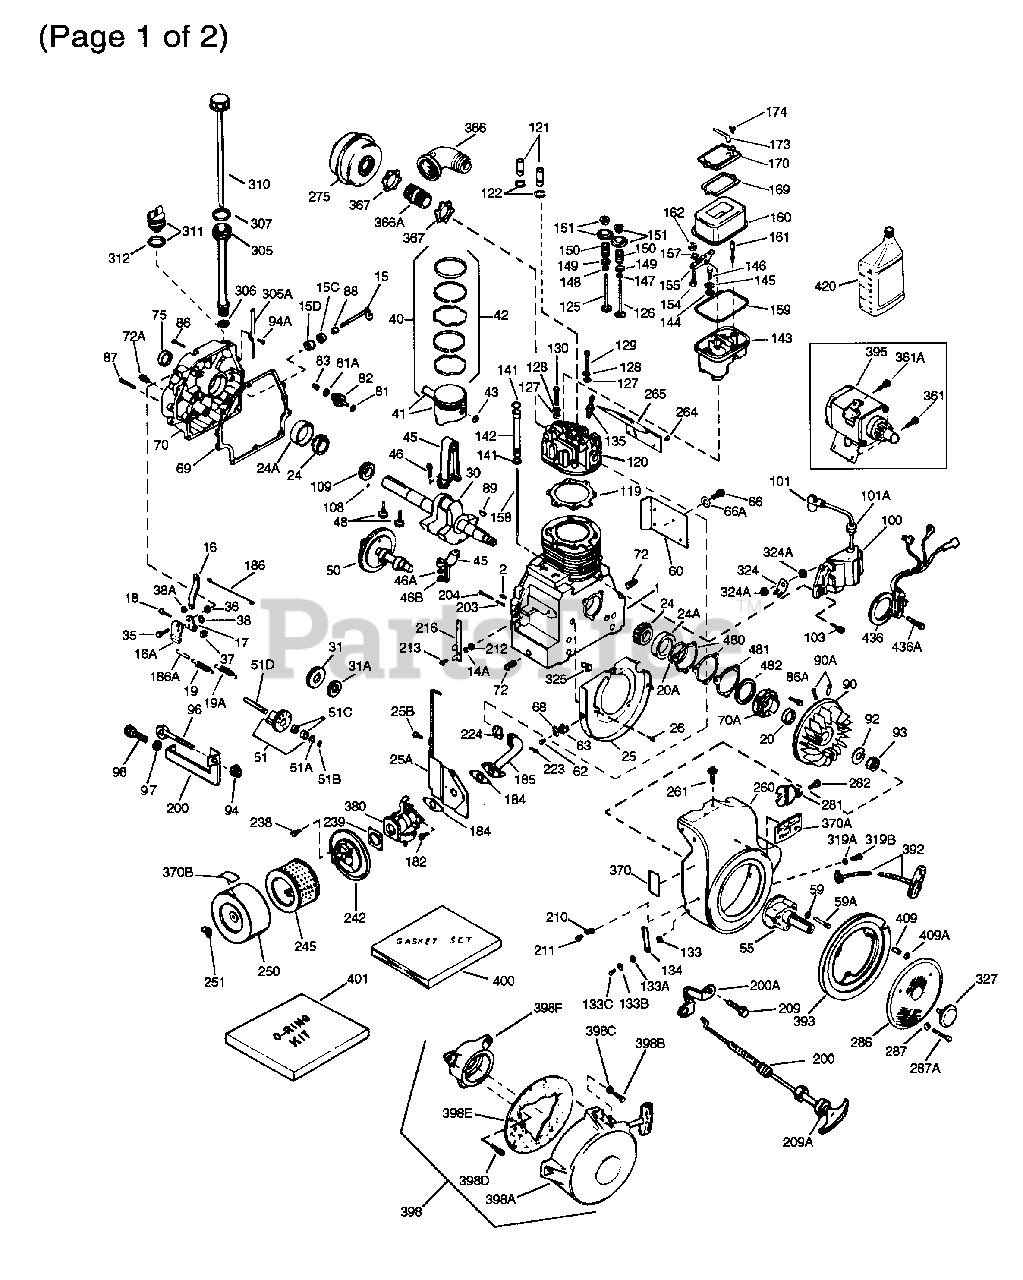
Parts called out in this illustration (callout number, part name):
1	"Cylinder (Incl. 2, 20 & 72)
2	Dowel Pin
15	Governor Rod
16	Governor Lever
16B	Governor Spring Plate
17	Governor Lever Clamp
18	Screw, Torx T-25, 10-24 x 7/8"
19	Extension Spring
20	* Oil Seal
20A	* "O" Ring
24	Tapered Roller Bearing
24A	Bearing Cup
25	Blower Housing Baffle
25A	Air Baffle
25B	Screw, 1/4-20 x 5/8"
26	Screw, 1/4-20 x 5/8"
30	Crankshaft
35	Screw, 10-32 x 1/2"
37	Lock Nut, 10-24
38	Retaining Ring
40	Piston, Pin & Ring Set (Std.)
40	Piston, Pin & Ring Set (.010" OS)
40	Piston, Pin & Ring Set (.020" OS)
41	Piston & Pin Ass'y. (Std.) (Incl. 43)
41	Piston & Pin Ass'y. (.010" OS) Incl. 43
41	Piston & Pin Ass'y. (.020" OS) Incl. 43
42	Ring Set (Std.)
42	Ring Set (.010" OS)
42	Ring Set (.020" OS)
43	Piston Pin Retaining Ring
45	Connecting Rod Ass'y. (Incl.46 - 46B)
45	Connecting Rod Ass'y. (.010" US) Incl . 46-46B
45	Connecting Rod Ass'y. (.020" US) Incl . 46-46B
46	Connecting Rod Bolt
48	Valve Lifter
50	Camshaft (MCR)
66	Screw, T-30, 1/4-20 x 1/2"
69	* Cylinder Cover Gasket
70	Cylinder Cover Incl. 15,15C,15D,36,38 ,75&88
70A	Cylinder Cover (See Ref. #'s 480-482)
72	Oil Drain Plug
72A	Oil Drain Plug
75	Oil Seal
82	Governor Gear Ass'y.
83	Governor Spool
86	Screw, 1/4-20 x 2"
86A	Screw, 5/16-18 x 7/8"
87	Screw, 1/4-20 x 1"
89	Flywheel Key
90	Flywheel (W/Ring Gear) (Incl. 90A)
90A	Trigger Pin Kit
92	Washer
93	Flywheel Nut
100	Solid State Ignition Incl. 101,101A,3 24,324A
101	Spark Plug Cover
101A	Grommet
103	Screw, 1/4-20 x 3/4"
108	Pin, Crankshaft gear
109	Crankshaft Gear
119	* Cylinder Head Gasket
120	Cylinder Head
121	Valve Guide Kit (Incl. 2 of 122)
122	Retaining Ring
125	Exhaust Valve (Std.) (Incl. 151)
125	Exhaust Valve (1/32" OS) (Incl. 151)
126	Intake Valve (Std.) (Incl. 151)
126	Intake Valve (1/32" OS) (Incl. 151)
128	Belleville Washer
129	Screw, 5/16-18 x 1-3/4"
130	Screw, 5/16-18 x 1-3/8"
133B	Washer
133C	Screw, 5/16-24 x 3/8"
135	Resistor Spark Plug (RL82C)
141	* "O" Ring (Also Incl. in 401)
142	Push Rod Tube
143	Rocker Arm Housing
144	* "O" Ring (Also Incl. in 401)
146	Screw, 1/4-20 x 29/32"
147	* "O" Ring (Also Incl. in 401)
148	* "O" Ring (Also Incl. in 401)
149	Valve Spring Cap
150	Valve Spring
151	Valve Spring Keeper
154	Rocker Arm Stud
155	Rocker Arm
157	Retaining Ring
158	Push Rod
159	* "O" Ring (Also Incl. in 401)
160	Rocker Arm Housing
161	Screw, 1/4-20 x 3/4"
162	Nut, 1/4-20
169	* Valve Cover Gasket (Also Incl.in 401)
170	Breather Body
173	Breather Tube
174	* Screw, 10-32 x 5/8" Also Incl. in 40 1
182	Screw, Torx T-30, 5/16-18 x 1-1/8"
184	* Carburetor To Intake Pipe Gasket
185	Intake Pipe
186	Governor Link
203	Compression Spring
204	Screw, 10-24 x 2"
210A	Conduit Clip
211A	Screw, 10-32 x 3/8"
212	Bushing
213	Screw, 10-24 x 5/8"
216	R.P.M. Adjusting Lever
223	Screw, Torx T-30, 5/16-18 x 7/8"
239	* Air Cleaner Gasket
245	Air Filter
250	Air Cleaner Cover
251	Wing Nut, 1/4-20
260	Blower Housing
261	Screw, 1/4-20 x 7/16"
261A	Screw, 1/4-20 x 7/16"
264	Screw, 1/4-20 x 1/2"
265	Cylinder Head Cover
286	Starter Screen
287	Lockwasher
287A	Screw, 1/4-20 x 1-1/2"
305	Oil Fill Tube
307	"O" Ring
310	Dipstick
319A	Lock Washer
319B	Screw, 5/16-24 x 3/8"
324	Terminal
324A	Nut, 8-32
355	Starter Handle
361	Screw, 5/16-18 x 11/16"
361A	Screw, 5/16-18 x 1/2"
366	Exhaust Elbow
370	Instruction Decal
370A	Decal - XL/C Industrial/Commercial
370B	Decal - Important Lubrication - SAE 3
380	Carburetor (Incl. 184)
392	Starter Rope
393	Starter Rope Pulley
395	Electric Starter Motor (12 Volt)
400	* Gasket Set (Incl. items marked PK in notes) Incl. part #'s 29673 (1), 3010 2 (2), 31950 (2), 31956B (1), 31958A (1), 31971 (2), 31972 (1), 32031 (1), 32599 (1), 33476A (2), 33481 (4), 33 484 (3), 33487 (1), 33509 (1), 33515A (1), 34225A (1), 34302A
401	* "O" Ring Set (Also Incl. in 400) 3010 2 (2), 31958A (1), 33481(4), 33484 (3 ), 33487 (1), 33509 (1) 34410 (1)
420	SAE 30 4-Cycle Engine Oil (Quart)
480	* Shim Gasket (.004/.005) See Repair M anual
481	* Shim Gasket (.005/.007) See Repair M anual
482	* Steel Spacer (.010) See Repair Manua l
